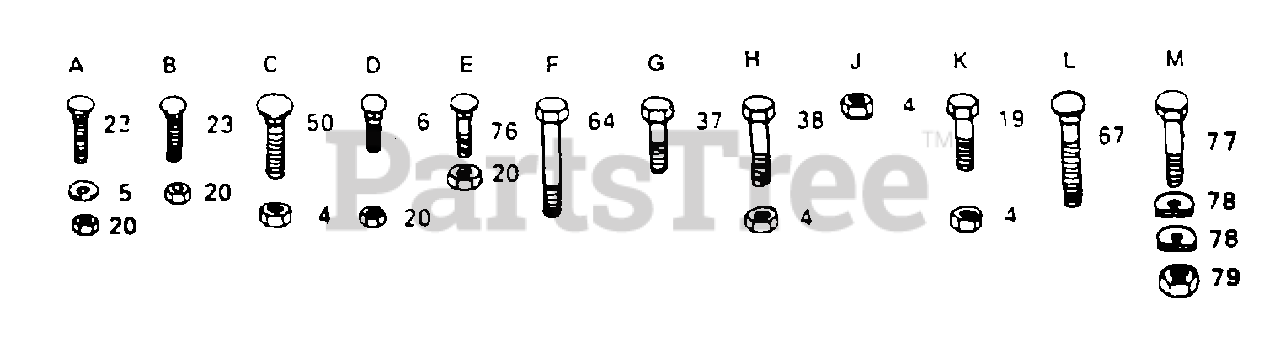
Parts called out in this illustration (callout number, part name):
5	WASHER M
6	BOLT
22	BRACKET LH T
23	BOLT
37	SCREW
38	SCREW
50	BOLT
64	BOLT
67	BOLT.3/8-14X1.25
77	BOLT LT
78	WASHER T
